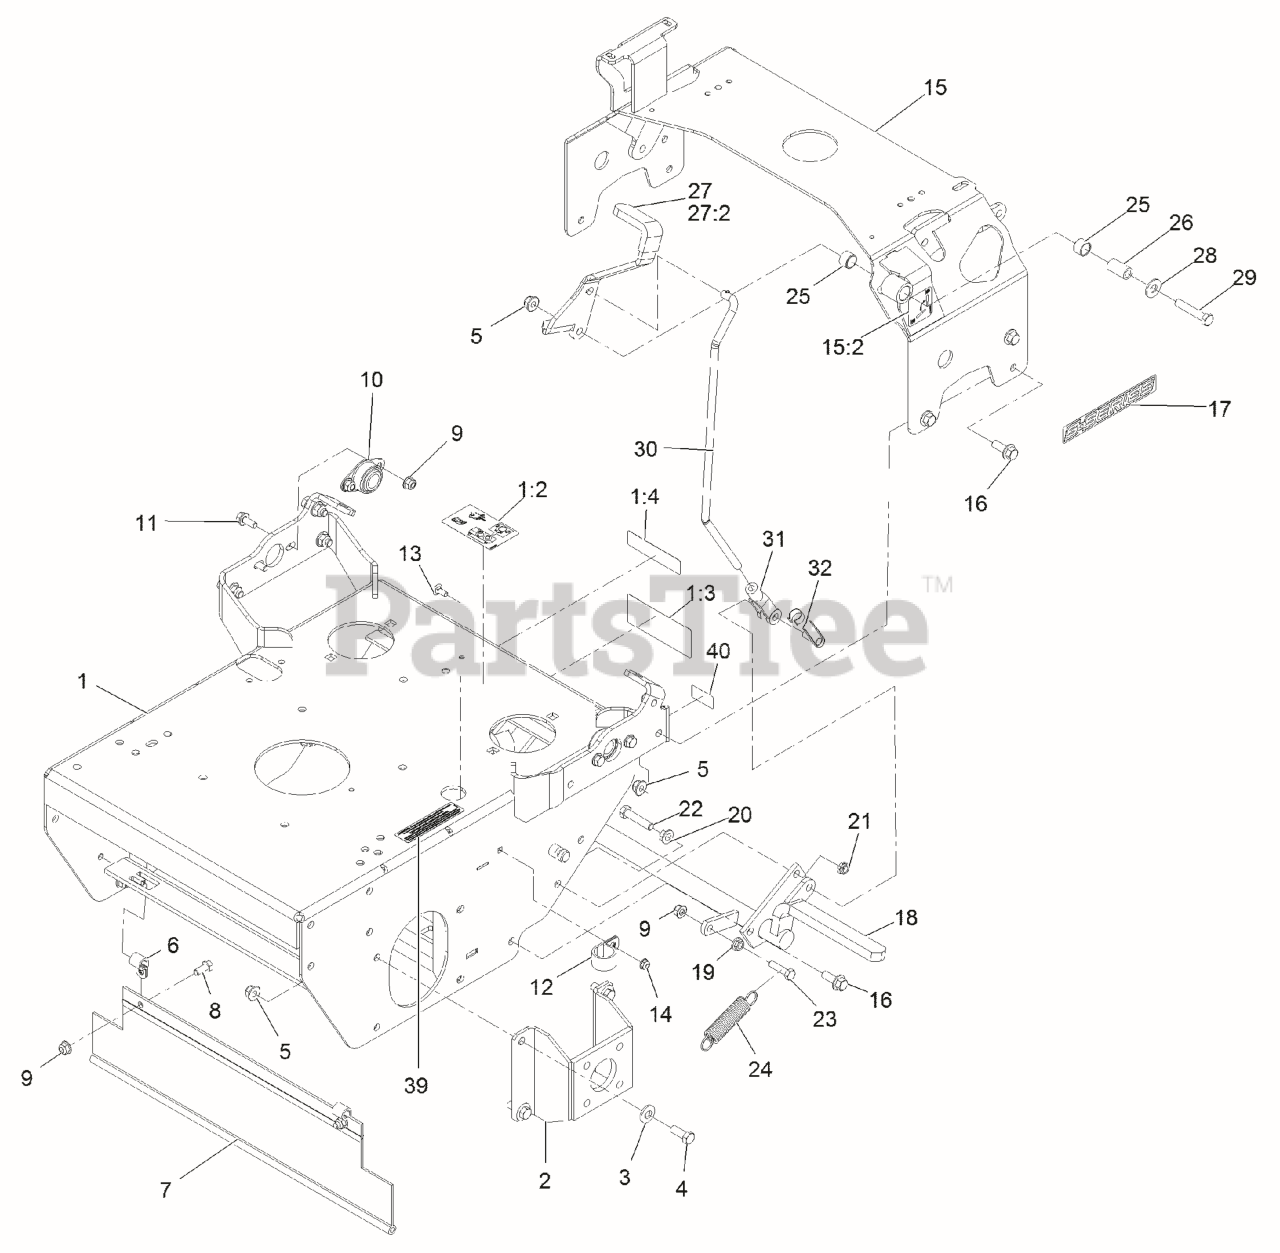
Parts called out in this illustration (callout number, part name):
1	ASM, ENGINE DECK W/ DECAL
1:2	DECAL-DRIVE RELEASE
1:3	DECAL-WARNING, SULKY
1:4	DECAL-WARNING
2	WLD,MOTOR MOUNT 48&52
3	WASHER-BELLEVILLE
4	SCREW-HH
5	NUT-HF, NI
6	CLIP-LOOM
7	SHIELD-DRAG
8	SCREW-HH
9	NUT-HF, NI
10	BEARING-FLANGE, SIDE
11	SCREW-HHF
12	CLIP-LOOM
13	SCREW-CARR
15	ASM, TANK SUPPORT W/ DECA
15:2	DECAL-PARK BRAKE, CE
16	SCREW-HHF 3/8-16 X 1
17	DECAL-S-SERIES
20	NUT-HHF, WHIZ
21	NUT-LOCK, NI
22	SCREW-HH
23	SCREW-HH
24	SPRING-IDLER
25	SLEEVE-BUSHING
26	BUSHING-PIVOT
27	ASM, BRAKE LEVER W/ GRIP
27:2	GRIP-LEVER
28	WASHER-FLAT
29	SCREW-HH
30	LINKAGE, BRAKE
31	YOKE-LINKAGE, BRAKE
32	PIN-SPRING, CLEVIS
39	DECAL-ARRESTER, SPARK
40	Decal-Patent
